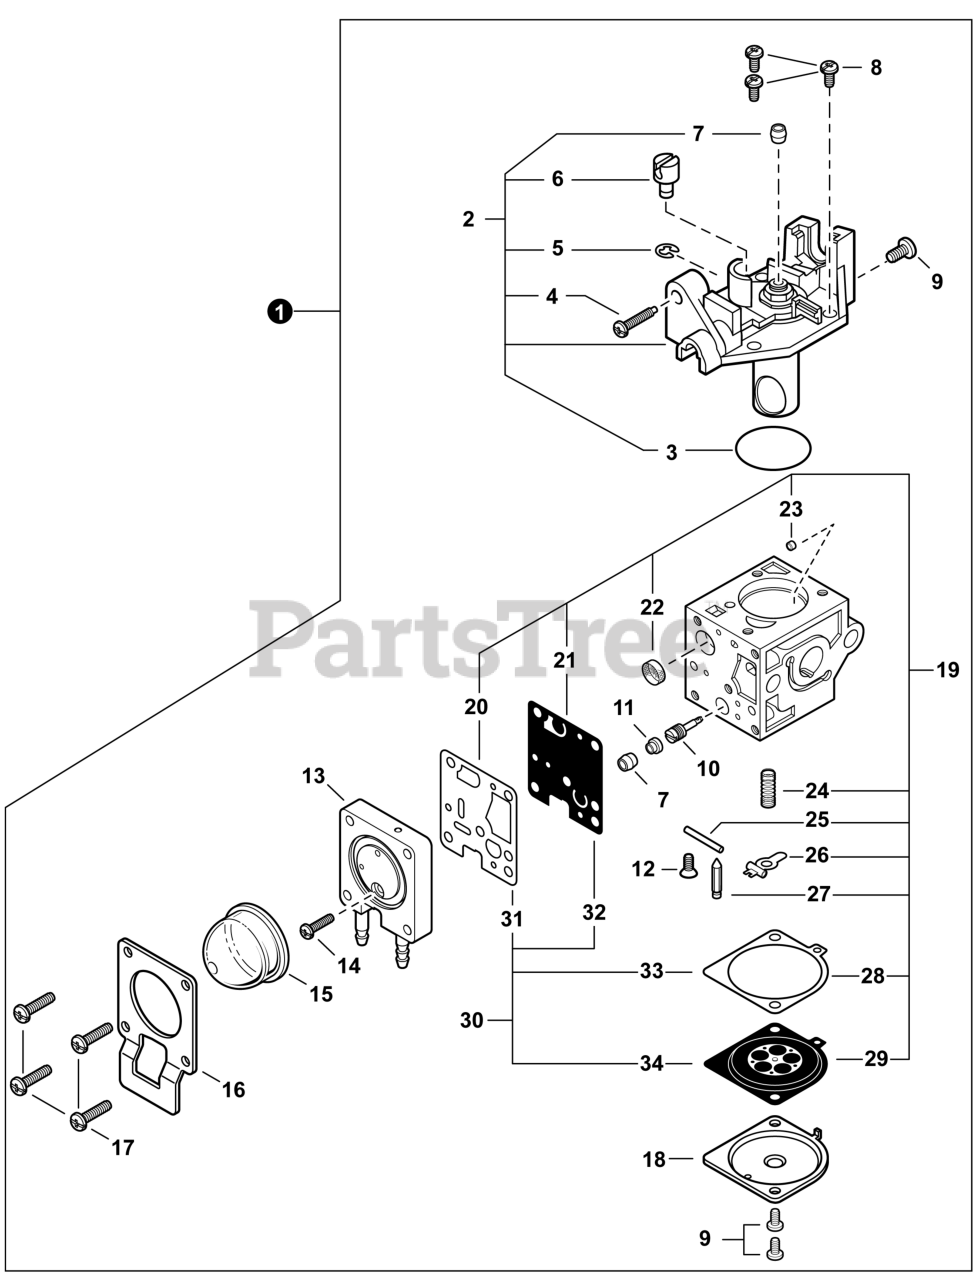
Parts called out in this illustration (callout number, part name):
1	CARBURETOR - Z011-0QA
2	COVER KIT, ROTOR
4	SCREW, IDLE ADJUST
10	NEEDLE, HIGH SPEED
11	CAP, LIMITER
13	BODY ASSY, PURGE
15	BULB, PURGE
16	RETAINER, PURGE BULB
18	COVER, METERING DIAPHRAGM
19	REPAIR KIT, CARBURETOR
20	GASKET, PUMP
21	DIAPHRAGM, PUMP
22	SCREEN, FUEL INLET
23	GUIDE, ROLLER
24	SPRING, METERING LEVER
25	PIN, METERING LEVER
26	LEVER, METERING
27	VALVE, INLET NEEDLE
28	GASKET, METERING DIAPHRAGM
29	DIAPHRAGM, METERING
30	GASKET / DIAPHRAGM KIT
31	GASKET, PUMP
32	DIAPHRAGM, PUMP
33	GASKET, METERING DIAPHRAGM
34	DIAPHRAGM, METERING
